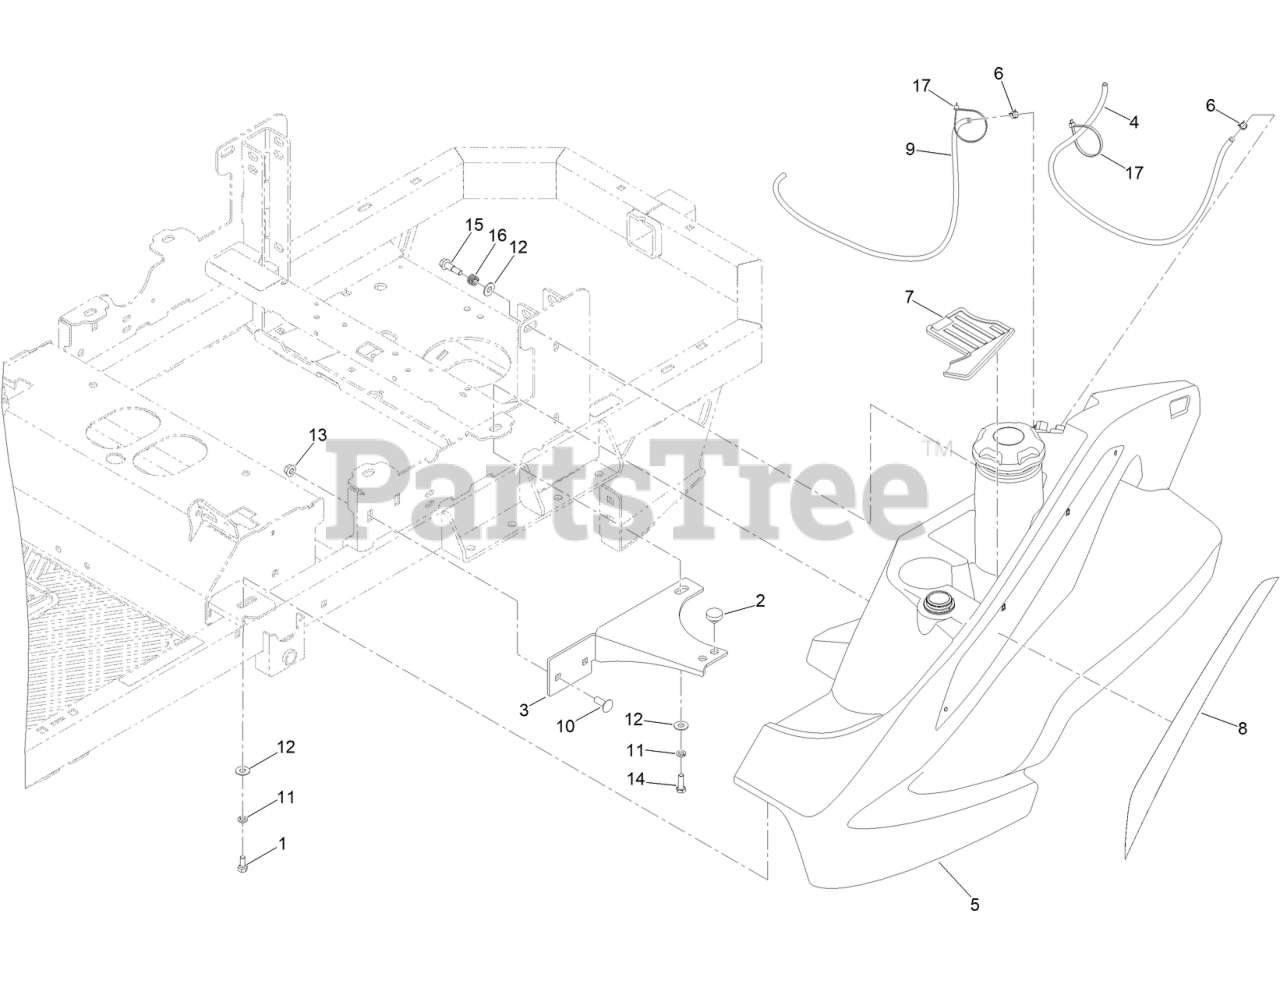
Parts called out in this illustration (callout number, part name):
1	SCREW-HH
2	PUSH-IN RUBBER BUMPER MWR FLOOR
3	BRACKET-TANK SUPPORT
4	MWR FUEL TANK BLACK 3/16IN VENT TUBE 1FT
5	MWR GASOLINE FUEL TANK ASSY
6	1/2IN (#8) HOSE CLAMP
7	RUBBER TANK STORAGE COMPARTMENT INSERT
8	DECAL-TANK
9	1/4IN SAE J30R7 BULK HOSE 1FT
10	3/8-16 X 1 CARRIAGE BOLT YZ GR.8
11	WASHER-LOCK
12	WASHER-FLAT
13	3/8-16 HEX FLANGE NUT W/SERR ZINC YELLOW
14	SCREW-HH
15	SCREW-SHOULDER,HHF
16	SPRING-COMPRESSION
17	TIE-CABLE
